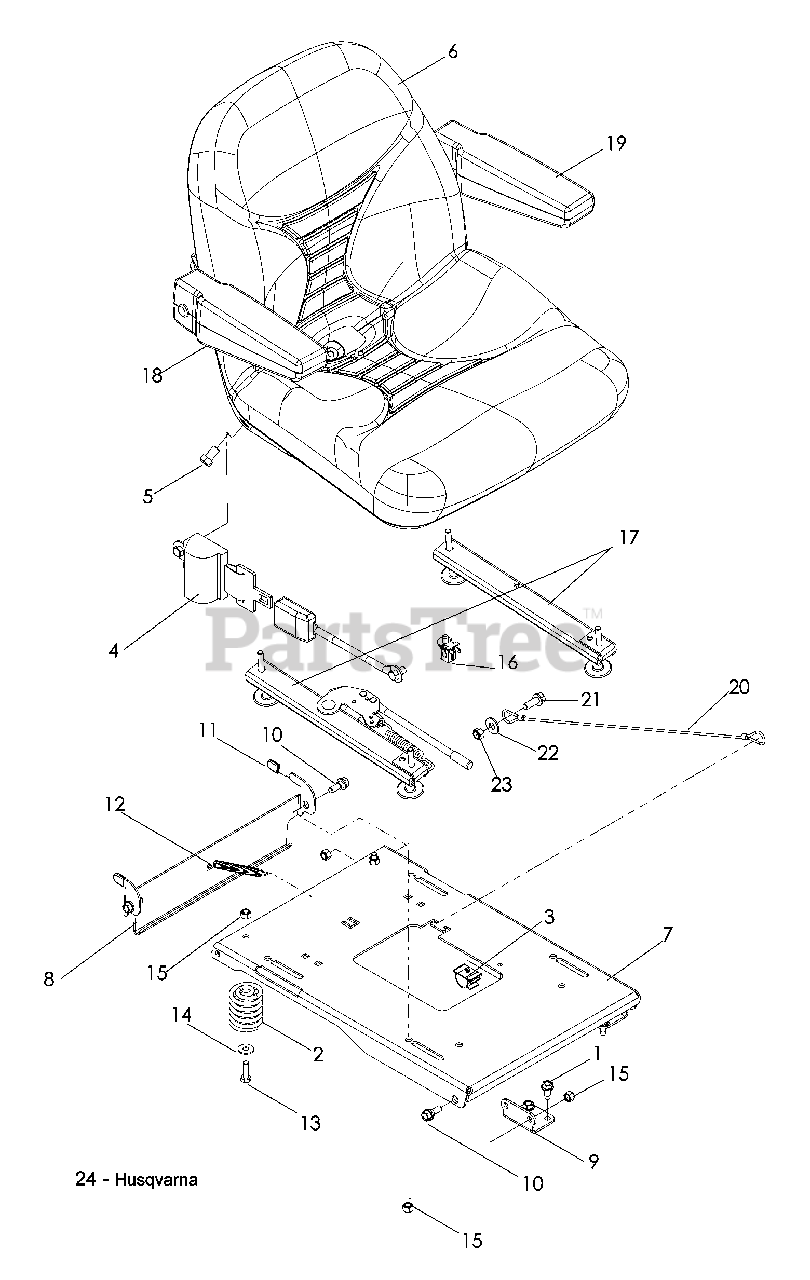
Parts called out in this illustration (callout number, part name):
1	BOLT 5/16-18 x ¾ THD FRM
2	SPRING, SEAT
3	CLIP, PUSH MOUNT
4	SEAT BELT, RETRACTABLE
5	HCS 7/16-20 x ¾
6	SEAT
8	LATCH, SEAT
9	PIVOT, SEAT PAN
10	BOLT 5/16-18 HEX HD
11	GRIP, VINYL
13	HCS 5/16-18 x 1
14	WASHER 5/16 STD FLT
15	NUT 5/16-18 HEX NYLOC
16	SWITCH, SEAT
17	SEAT RAIL SET COMPLETE
18	ARM REST ASSM, RT
19	ARM REST ASSM, LT
20	SEAT LANYARD
21	HCS, 3/8-16 x 1 WHIZLK
22	WASHER 3/8 STD FLT
23	NUT 3/8-16 HEX NYLOC
